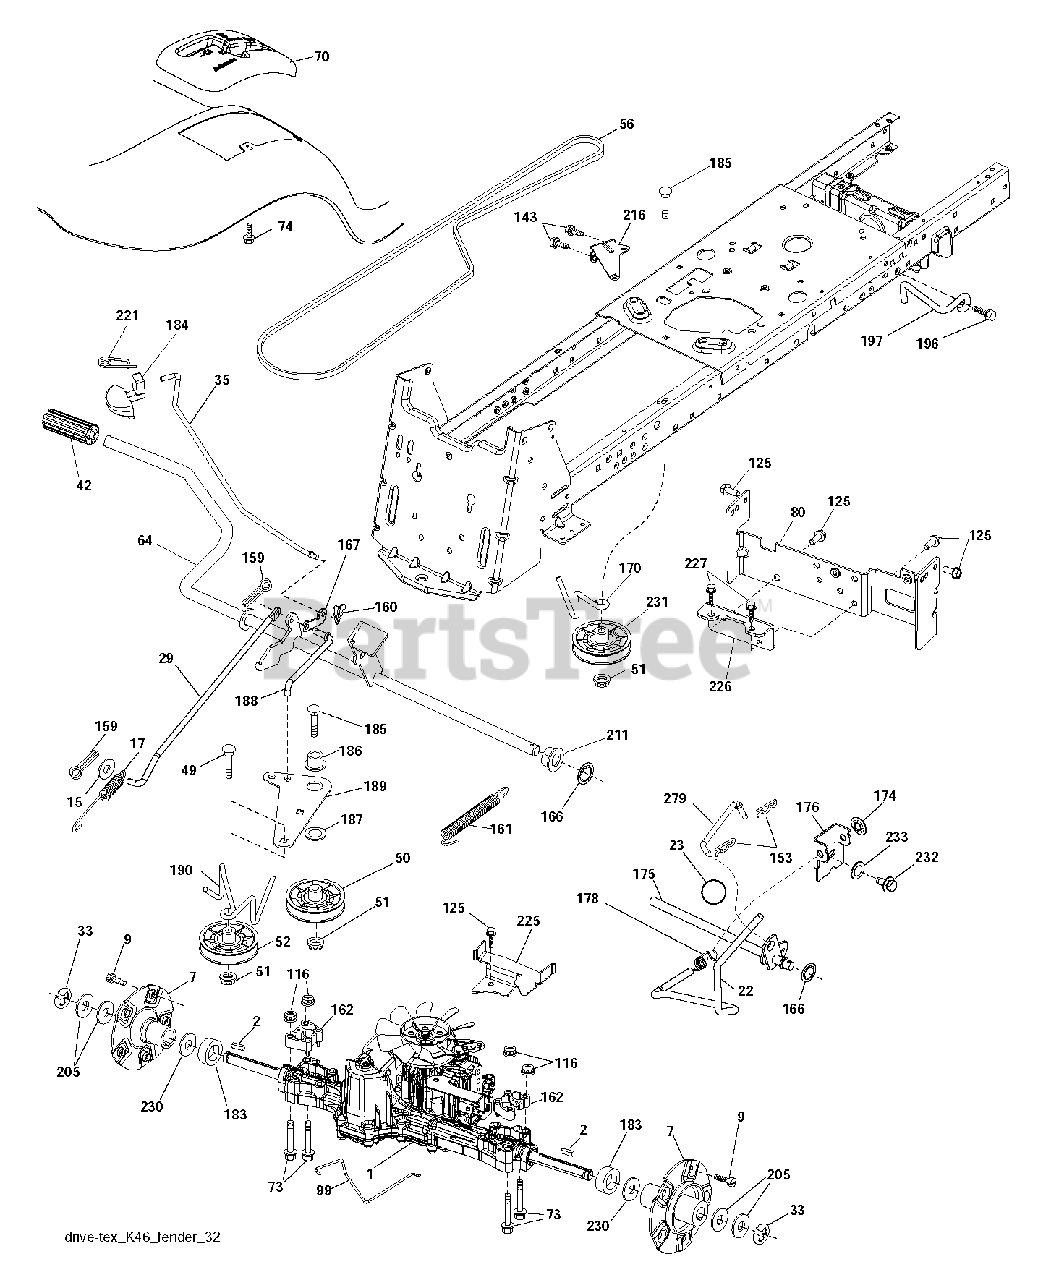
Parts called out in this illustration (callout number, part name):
2	KEY.SQUARE.187X2.500
7	HUB.ASM.WHEEL.REAR.22"
9	HUB BOLT
17	SPRING.BRAKE.K46.GREEN
22	ROD.SHIFT.FENDER.STGT.
23	KNOB.DELUXE.(PISTOL.GRIP).BLAC
29	ROD.BRAKE.K46
33	E RING HYT
35	ROD.BRAKE.PARKING.LT.T
49	BOLT
50	IDLER.FLAT.910.OFFSET
51	NUT LOCK FLG 3/8-16 UNC
52	IDLER.V-GROOVE.910.OFFSET
56	V-BELT.MOWER.92.40.42/K46
64	SHAFT.ASM.PEDAL.BRAKE.
70	PAD.FOOTREST.RH.STGT.BLACK
73	Hex Flange Bolt, 5/16-18 X 3.75
74	SCREW.HI-LO.CONSOLE
80	STRAP.TORQUE.K46.K57R.TT
99	ROD.SPRING.BYPASS.K66.GT.Z
116	NUT LOCK HEX FLANGE 5/16-18
125	SCREW
143	SCREW LT
159	COTTER PIN
160	RETAINER CLIP
161	SPRING, RETURN LT
162	SPACER.TRANSAXLE.18&22
166	NUT.PUSH.625
167	LATCH.BRAKE.SPRING
170	KEEPER.CENTER SPAN.1.688
174	NUT.PUSH.500.2006
175	SHAFT ASM SHIFT
176	ARM.CLEVIS.ROD.SHIFT
178	SPRING.SHIFT.GT2006
183	SPACER.SPLIT.800X.350
184	HANDLE.PARKING.BRAKE.LTTEX.667
186	SPACER.RETAINER
187	WASHER 12/32X2X10GA
188	LINK.CLUTCH.GROUND.DRIVE
189	BELLCRANK.GROUND.DRIVE.TEX.
190	KEEPER.BELLCRANK.DRIVE
196	SCREW 3/8-16X1
197	BRKT.ANIT-ROTATION.CLUTCH
211	BUSHING.SHAFT.BRAKE.HAND
216	BRACKET.PULLEY.IDLER.W/TEX
221	RETAINER.SPRING.CLIP.H
225	KEEPER.BELT.TRANSAXLE.K46
226	BRKT.MOUNT.TORQUE.K46.
227	Screw, Lt
230	WASHER.HARDENED
231	IDLER.V-GROOVE.1.688.OFFSET
232	BOLT FIN HEX 7/16-14 X 1
233	WASHER SERRATED
279	LINK.SHIFT.T/A.K46.FEND.TX
